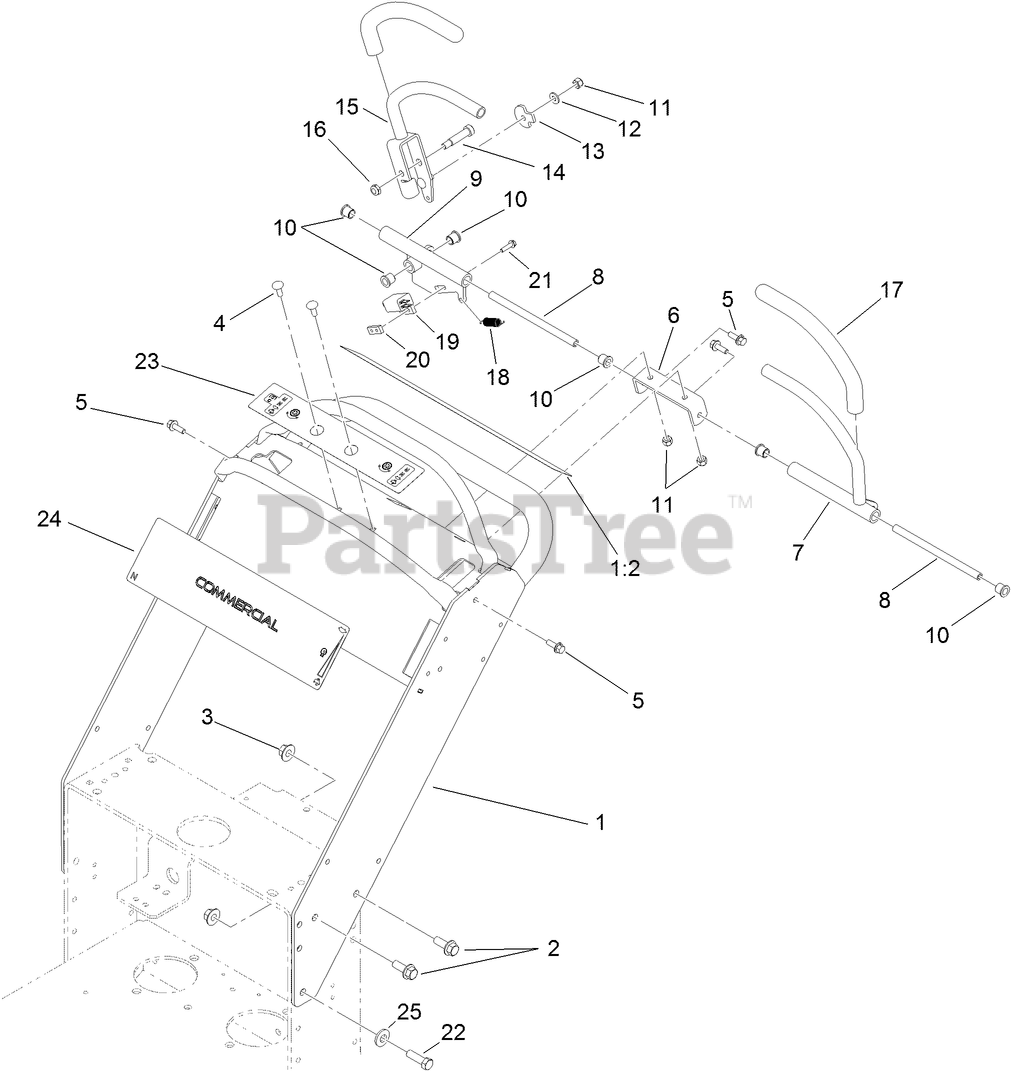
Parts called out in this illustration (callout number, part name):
1	HANDLE ASM
1:2	DECAL-WARNING, CONTROL
2	SCREW-HHF
3	NUT-HF
4	BOLT-CARR
5	SCREW-HHF
6	BRACKET-SUPPORT
7	LEVER-CONTROL
8	SHAFT-PIVOT, MOTION CONTROL
9	MOTION CONTROL ASM
10	BEARING
11	NUT-LOCK, NI
12	WASHER-FLAT
13	CAM-LEVER
14	SCREW-HSH
16	NUT-LOCK, NI
18	SPRING-EXTENSION
19	SWITCH-CLOSED, NORMALLY
20	PLATE-TAPPED
21	SCREW-HWH
22	SCREW-HH
23	DECAL-CONTROL
24	DECAL-PANEL, CONTROL
25	WASHER-BELLEVILLE
